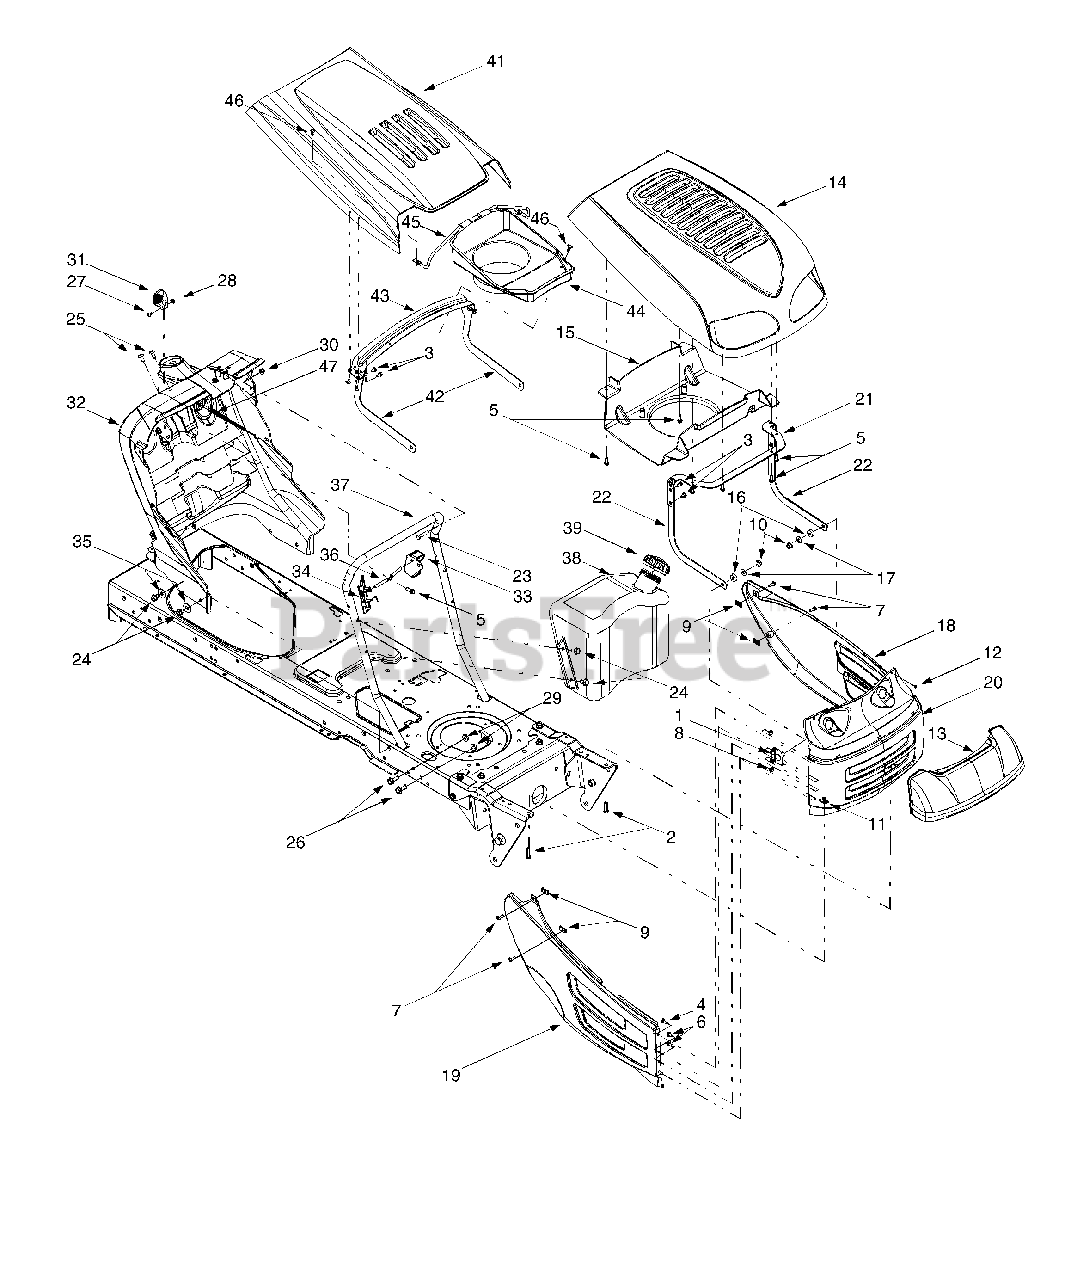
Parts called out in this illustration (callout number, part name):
2	Hex Cap Screw, 5/16-18 x 1.25
3	Self-tapping Screw, 1/4-20 x .5
4	Hex Cap Screw, 1/4-20 x .62
5	Self-tapping Screw, 1/4-15 x .75
6	Screw, 1/4-15 x .75
7	Phillips Pan Screw, 1/4-20 x .75
8	Hex Sems Nut, 1/4-20
9	U-type Speed Nut, 1/4-20
10	Flange Lock Nut, 3/8-16
11	U-nut, 5/16-18
12	Retainer Nut, 3/8
13	Headlight Lens
14	Hood, 7-style, Red
15	Hood Plenum, 7-style
16	Rubber Washer, .87 x .33
17	Bell Washer, .401 x .87 x .063
24	Self-tapping Screw, 5/16-18 x .625
25	Truss Phillips Screw, 1/4-20 x .625
26	Hex Washer Screw, 5/16-18 x .625
27	Truss Phillips Screw, #8-32 x .375
28	Hex Nut, #8-32
29	Flange Lock Nut, 5/16-18
30	Hex Flange Lock Nut, 1/4-20
31	Throttle Control Knob
32	Dash Panel
33	Parking Brake Button
34	Plastic Plug
35	Flat Washer, .349 x 1.0 x .063
36	Pivot Rod
39	Fuel Cap (Fits Either Tank)
45	Heat Shield Support Rod
46	Ratchet Clip
47	Choke Cable/Knob (Units w/ B&S Opposed Twin or OHV Twin)
